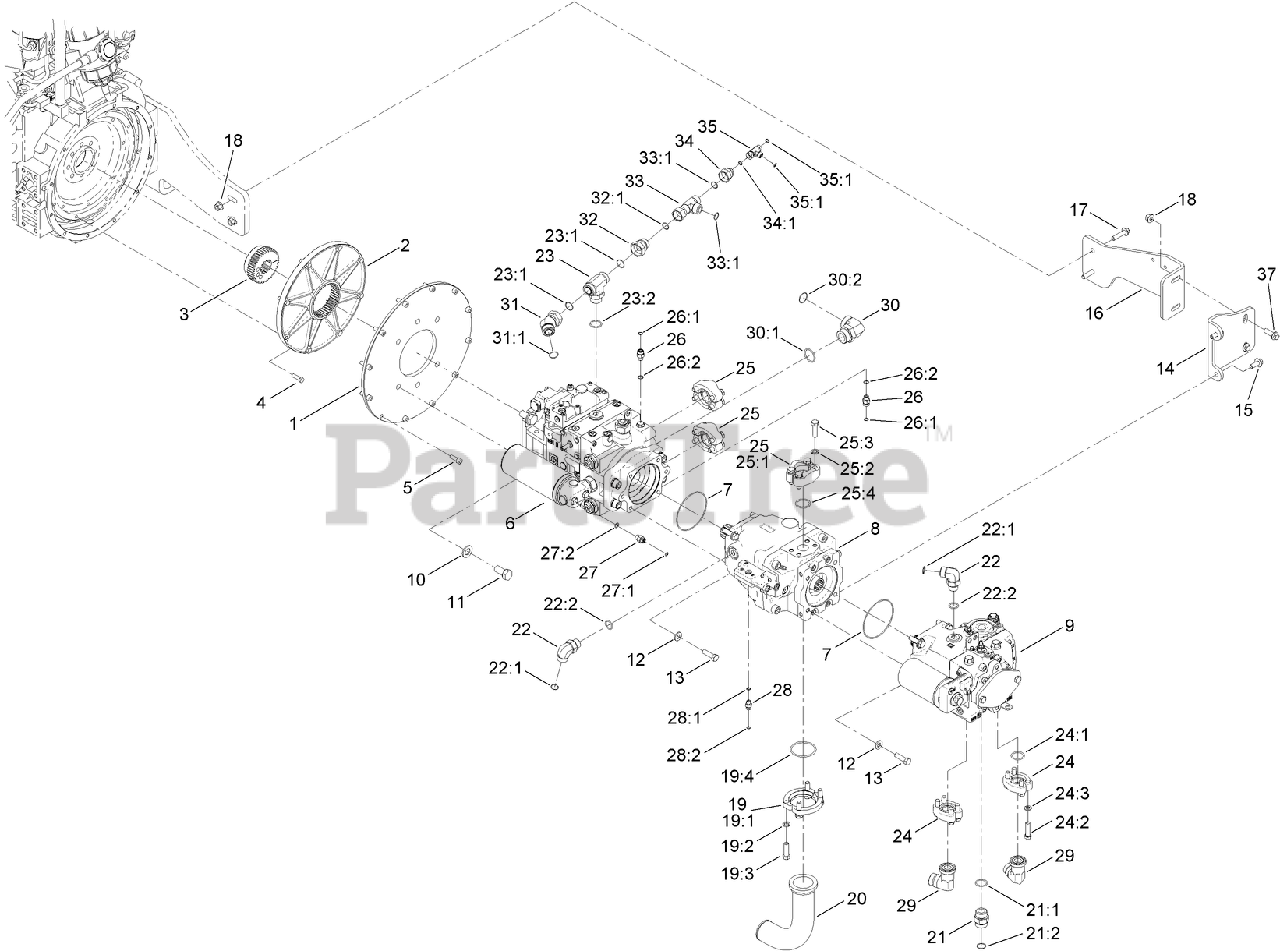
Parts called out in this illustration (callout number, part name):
1	PLATE-MOUNT, PUMP
2	COUPLING-DRIVE, NYLON
3	HUB-STEEL, 13T
4	SCREW-HH
5	SCREW-HSH
6	ROTARY PUMP ASM
7	SEAL-O RING
8	LOAD-SENSE PUMP ASM
9	HYDROSTAT PUMP ASM
12	WASHER-FLAT
13	SCREW-HH
14	BRACKET-MOUNTING, PUMP
15	SCREW-HHF
16	BRACKET-MOUNTING, CENTER
17	SCREW-HHF
18	NUT-LOCK, HHF
19	SPLIT FLANGE KIT
19:1	Flange
19:2	WASHER-LOCK
19:3	SCREW-HH
19:4	O-RING
20	TUBE-BENT
21	FITTING-STRAIGHT
21:1	O-RING
21:2	O-RING
22	FITTING-ELBOW-90
22:1	O-RING
22:2	O-RING
23	FITTING-HYD
23:1	O-RING
23:2	O-RING
24	FLANGE KIT
24:1	O-RING
24:2	SCREW-HH
24:3	WASHER-LOCK
25	SPLIT FLANGE KIT
25:1	FLANGE-HALF
25:2	WASHER-LOCK
25:3	SCREW-HH
25:4	O-RING
26	FITTING-STRAIGHT
26:1	O-RING
26:2	O-RING
27	FITTING-STRAIGHT
27:1	O-RING
27:2	O-RING
28	FITTING-STRAIGHT
28:1	O-RING
28:2	O-RING
29	ELBOW-90
30	FITTING-ELBOW 90
30:1	O-RING
30:2	O-RING
31	FITTING-ELBOW, 45
31:1	O-RING
32	FITTING-REDUCER
32:1	O-RING
33	FITTING-TEE
33:1	O-RING
34	FITTING-REDUCER
34:1	O-RING
35	FITTING-TEE, SWIVEL NUT
35:1	O-RING
37	SCREW-HHF
